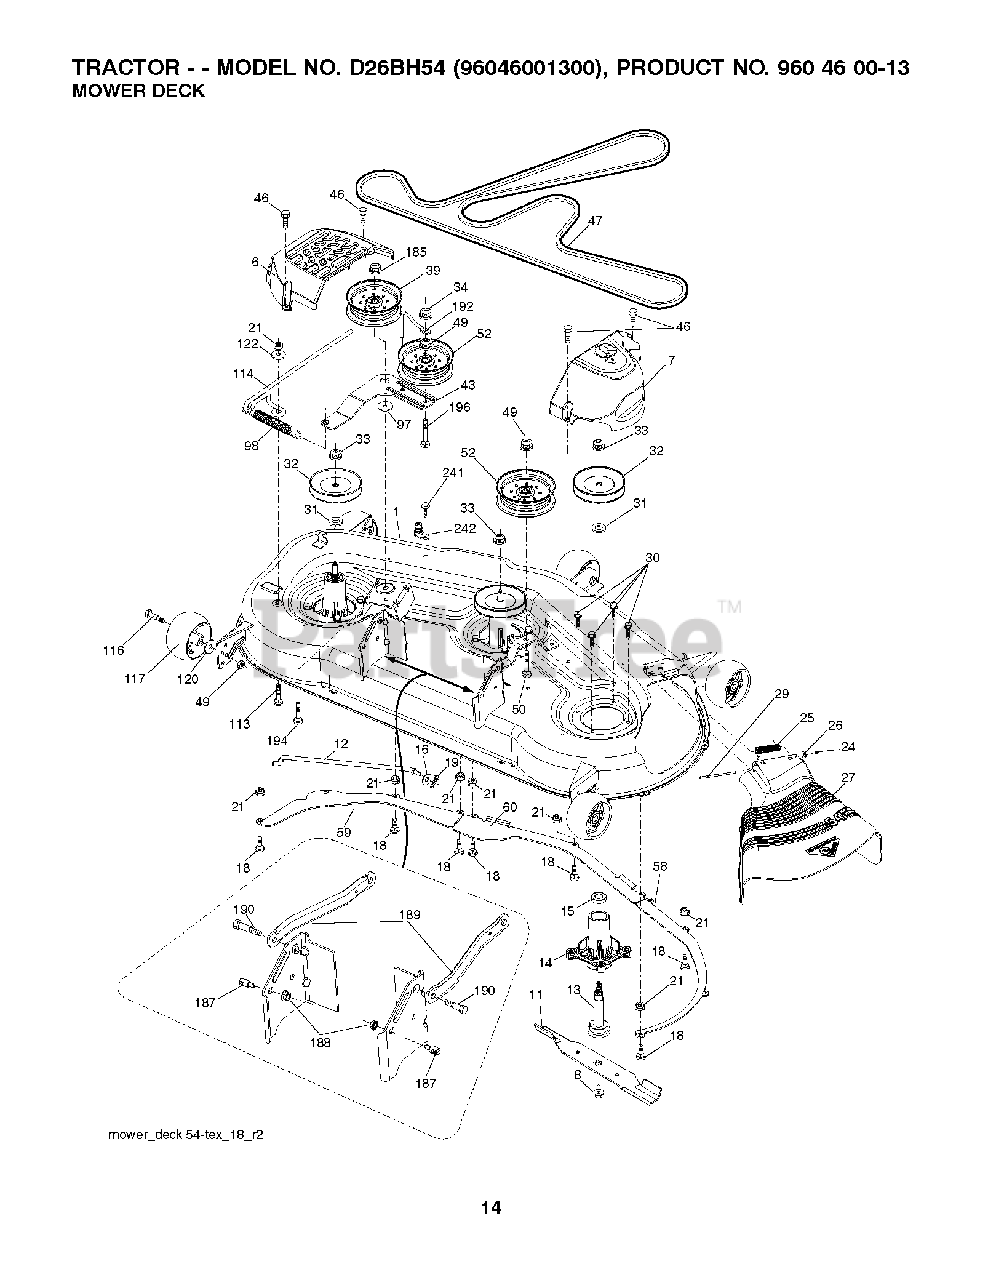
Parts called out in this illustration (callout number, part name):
1	DECK.WELDMENT.54".5GWB.BLUE
6	COVER.MANDREL.LH.54"20
7	COVER.MANDREL.RH.54.20
8	BOLT.WASHER.ASM.7/16-2
11	BLADE.BAGGING.54"
11	54" MULCH BLADE
12	ROD.ANTI.SWAY.48/54"TE
13	SHAFT ASM MANDREL
14	HOUSING.MANDREL.4PT.
15	BEARING
16	WASHER
18	BOLT
19	PIN.COTTER.5/16.BOW TI
21	LOCKNUT
24	CAP-SLEEVE LT
25	SPRING, TORSION
26	NUT PUSH M
27	Mower Deck Deflector for 54" Deck, Black
29	ROD.HINGE
30	SCREW, WASHER HEAD
31	WASHER.SPACER.MANDREL
32	PULLEY/MANDREL
33	NUT.FLANGE.LOCK.TOP
34	LOCKNUT
39	PULLEY.IDLER.4.50/HUB SPECIAL
43	ARM.IDLER
46	SCREW.1/4-20X5/8
47	BELT.DRIVE.54."2006
49	NUT LOCK FLG 3/8-16 UNC
52	PULLEY.IDLER.2006
58	BAFFLE.RIGHT.54"
59	BAFFLE.LEFT.54"
60	BAFFLE CENTER 54" MOWER
98	SPRING, DECK DRIVE
113	BOLT CRT
114	ROD TENSION RELIEF
116	BOLT.SHOULDER.3/8-16X3-5/8.
117	WHEEL. GUAGE RALLY
120	WASHER
122	BUSHING.RELIEF.TENSION
185	NUT.LOCK.FLANGE.7/16
187	STUD.FASTNER.W/ANTI-ROTATE
188	NUT LOCK HEX FLANGE 5/16-18
189	ARM.SUSPENSION.MOWER
190	BOLT.SHOULDER
192	KEEPER.BELT.IDLER.54"T
194	BOLT.CARR.SQNK.7/16
241	SCREW.TT.#10-32X.5.3/8.FLANGE
242	PORT.WASHOUT
